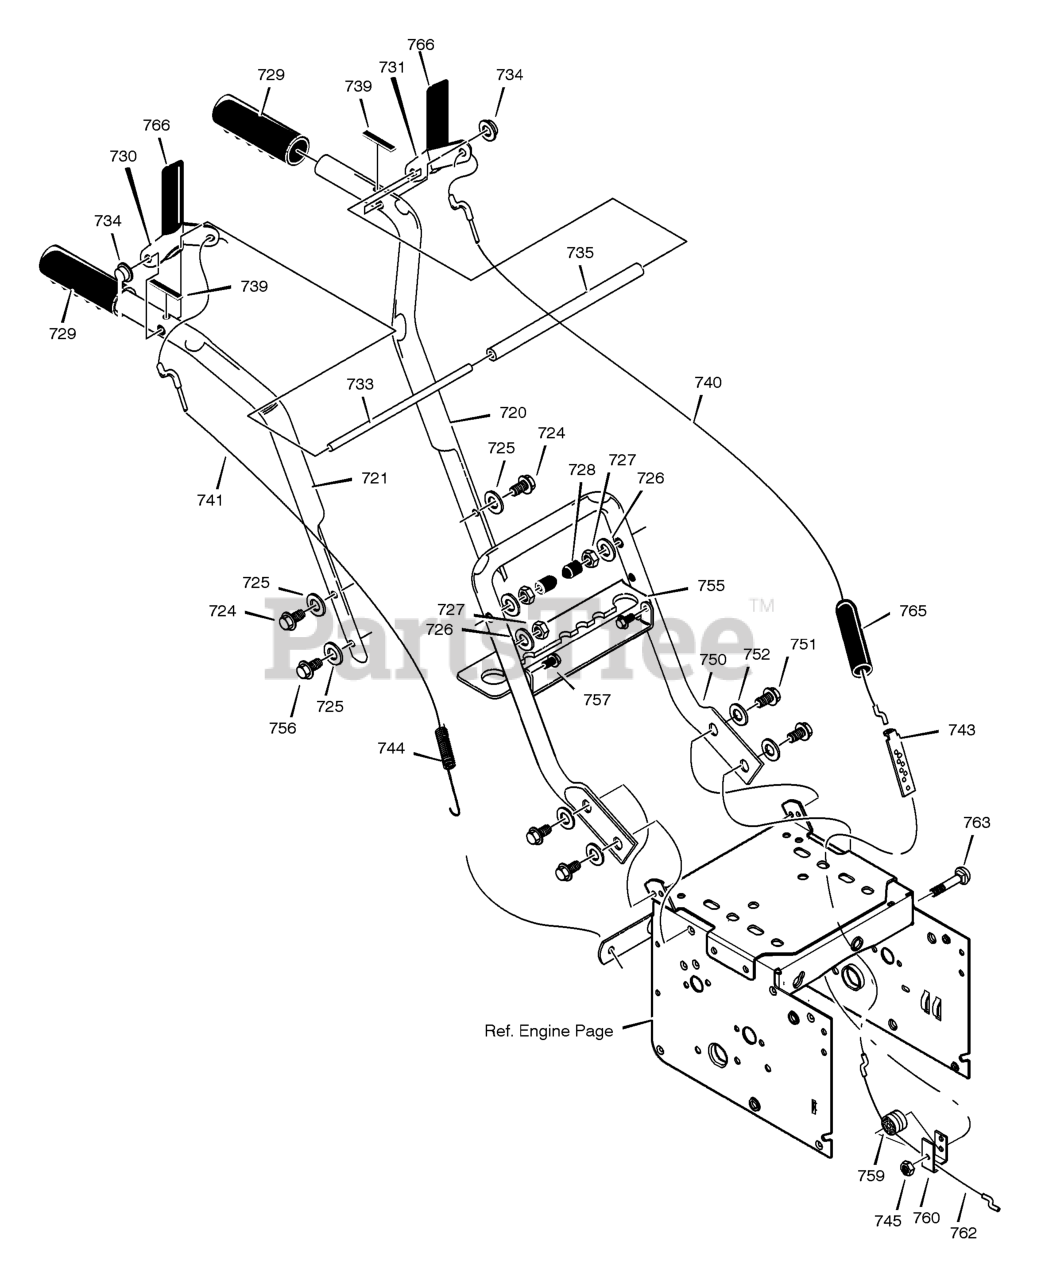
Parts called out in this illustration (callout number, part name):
720	HANDLE, UPPER LH
721	HANDLE, UPPER RH
724	SCREW, 5/16-18 x 2.75
725	WASHER, FLAT
726	WASHER, SPTLK .31X.58X.08
727	NUT, 5/16-18 REGHEX
728	STOP, RED PLASTIC
729	GRIP-HANDLE FINGER
730	LEVER, ASSY CLUTCH DRIVE RH
731	LEVER, ASSY CLUTCH DRIVE LH
733	ROD, PIVOT CLUTCH
734	NUT, PUSH ON CAP
735	SPACER-HANDLE
739	BUMPER, RECTANGLE
740	CABLE, CLUTCH 28.44L
741	CABLE, AUGER CLUTCH
743	BRACKET, CABLE ADJUSTER
744	SPRING, AUGER CLUTCH
745	NUT, 1/4-20
750	HANDLE, LOWER
751	SCREW, TAP 5/16-18 X .75
752	WASHER, SPTLK
755	BRKT, GEAR SELECTOR
756	SCREW, 5/16-18 x 2.00
757	SCREW, 1/4-20 x0.63
759	SPOOL-CABLE, AUGRT CLUTCH
760	BRACKET, CABLE SPOOL YZ
762	CABLE, LOWER DRIVE 12"
763	BOLT, HEX 1/4-20 X 1.75 YZ
765	BOOT, CLUTCH SPRING
